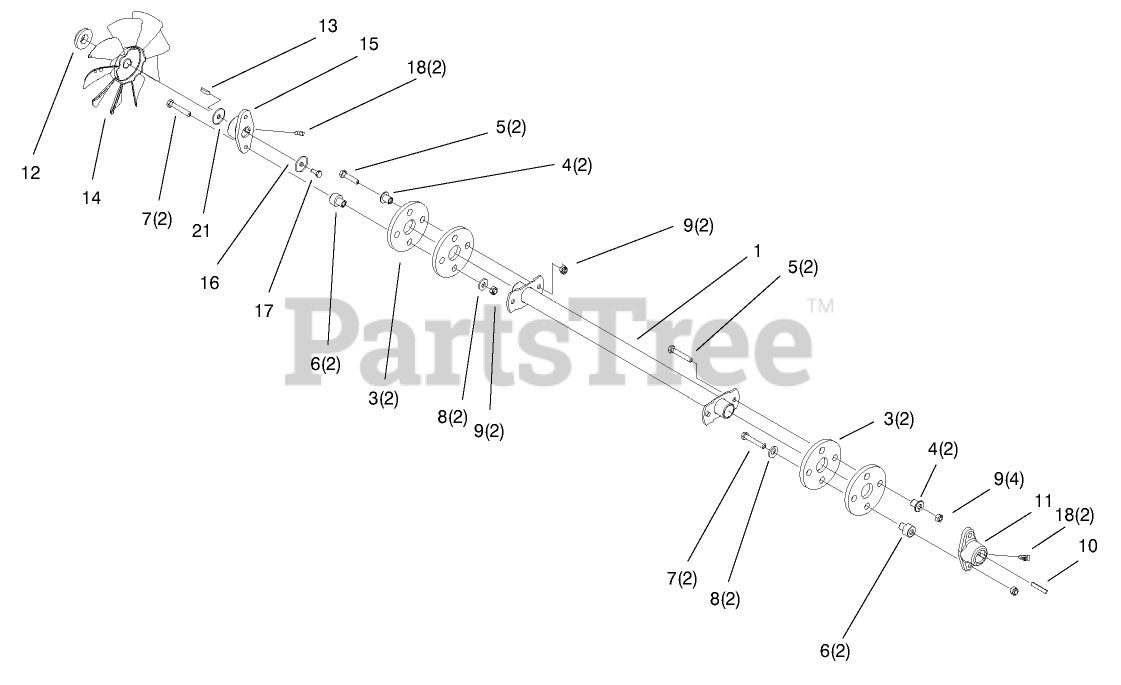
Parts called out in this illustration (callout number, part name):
1	SHAFT-DRIVE
4	SPACER
5	SCREW-HH
6	SPACER
7	SCREW-HH
8	WASHER-FLAT
9	NUT-LOCK, NI
10	KEY-SQUARE
12	SPACER-FAN
13	KEY-WOODRUFF
14	FAN-HYDRO
16	WASHER
17	SCREW-HH
18	SCREW-SET
